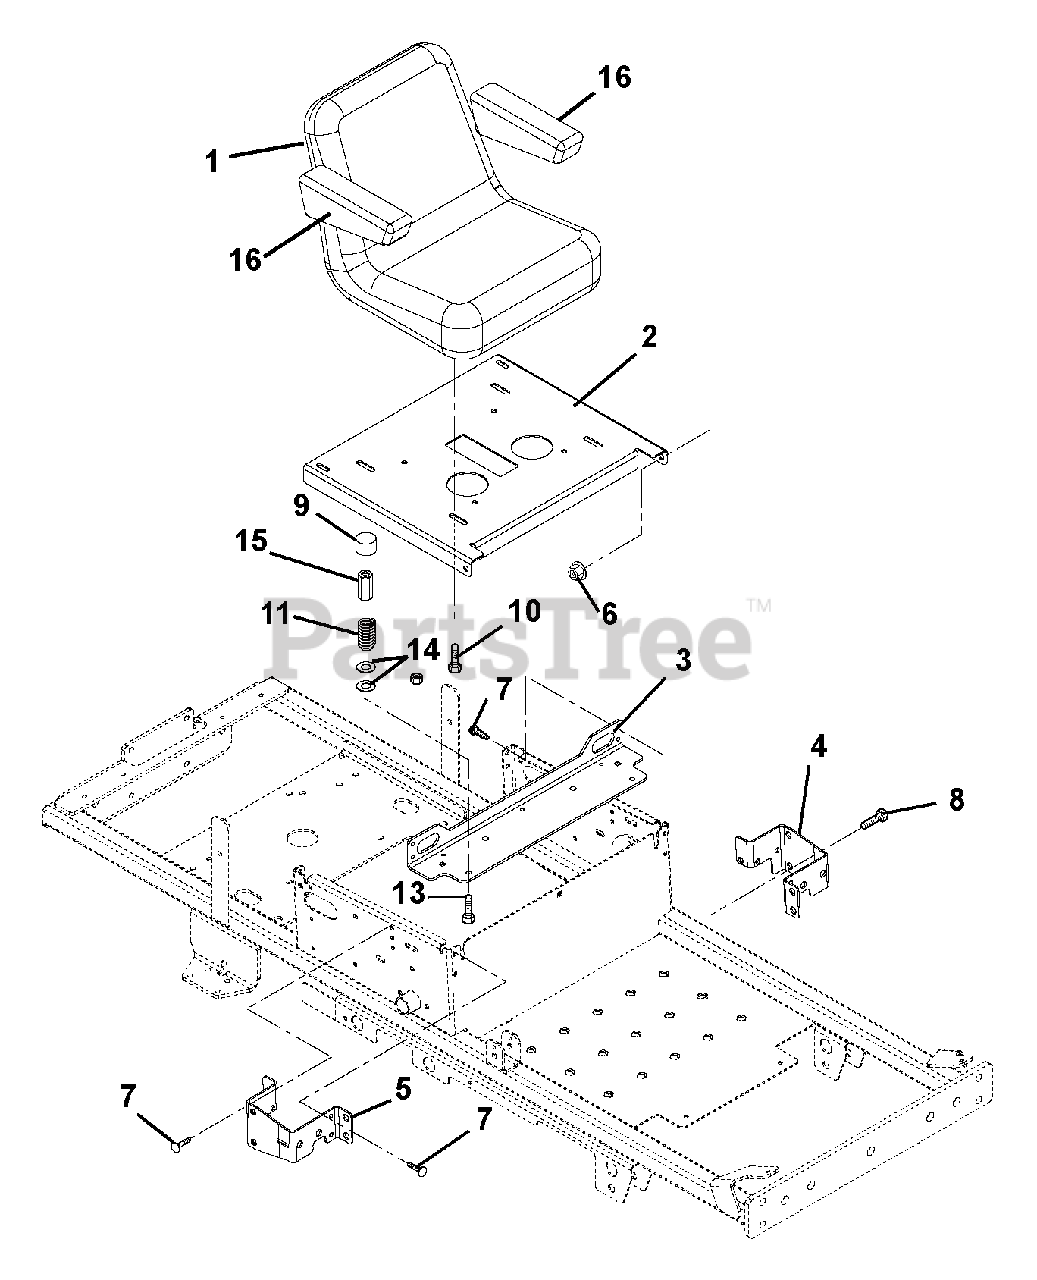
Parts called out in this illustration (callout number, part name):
1	SEAT,V-2505 MICHIGAN W/ARM
2	SEAT PLATE
3	BRKT, SEAT SPRING
4	WDMT, RH STEERING STOP
5	WDMT, LH STEERING STOP
6	@NUT-LK-TOP-FLG .38-16 YWZC
7	@SCR-TAP .31-18X.50 HWH TR YWZ
8	BOLT-SHLDR .375-16X.150
9	HUB CAP
10	5/16-18X3/4 HX/W/HD WHIZ
11	SPRING, SEAT
12	@NUT-LK-NYL-FLG .31-18 YWZC
13	@BLT-RDHDSQNK .31-18X1.50 G5YZ
14	WSHR-FL-STL .328X.87X.179 YWZC
15	NUT, COUPLING 5/16-18 X 1 3/4
16	KIT,ARMREST PAD ONLY 1 PER KIT
